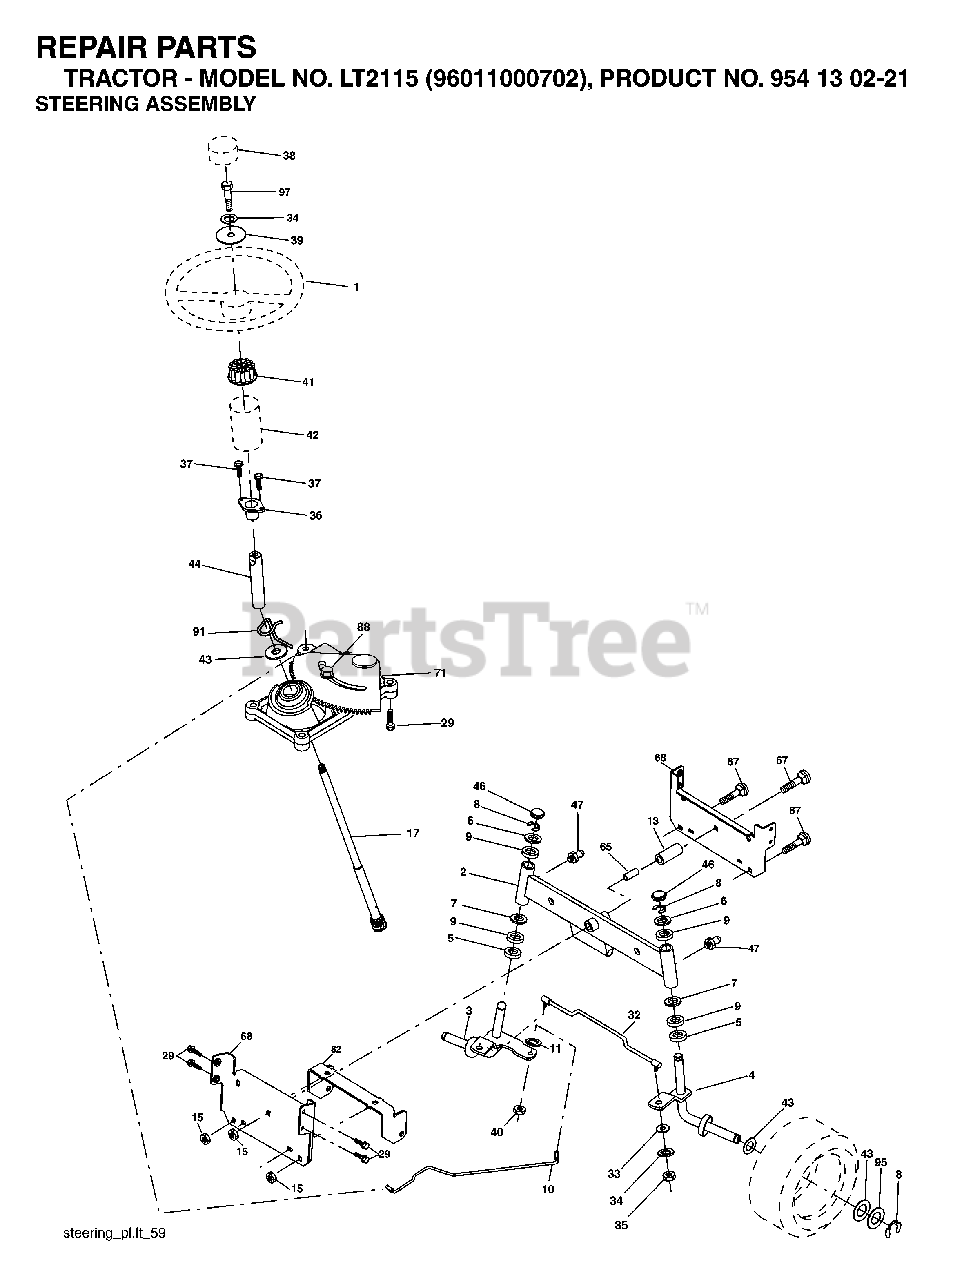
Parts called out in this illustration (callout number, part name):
2	AXLE ASM.
3	SPINDLE.ASM.LH.15"TIRES
4	SPINDLE.ASM.RH.15"TIRES
8	RING CLIP
9	BRNG T
10	DRAGLINK.15".TIRES.2001
11	WASHER, LOCK 3/8
13	TUBE, PIVOT AXLE
15	NUT
17	SHAFT STEERING SPLINE
29	SCREW, 3/8-16X3/4
33	WASHER M
34	LOCKWASHER
35	NUT, CROWNLOCK
36	BUSHING, STEERING
38	INSERT.CAP.STRG.WH.BLACK
39	WASHER.11/32
40	NUT CROWNLOCK 3/8-24
41	ADAPTER, WHEEL STNG..
42	BOOT.STEERING.SHAFT.BLACK
44	SHAFT.EXTEN.STRG.SPLINE
46	CAP.SPINDLE
47	FITTING.GREASE.TAPERED
65	SPACER BRACE AXLE
67	BOLT CARRIAGE
68	BRACE.AXLE.15"TIRES
71	STEERING ASM
82	BRACKET
88	BOLT, SHOULDER 7/16-20
91	CLIP.STEERING
95	WASHER.HARDENED
